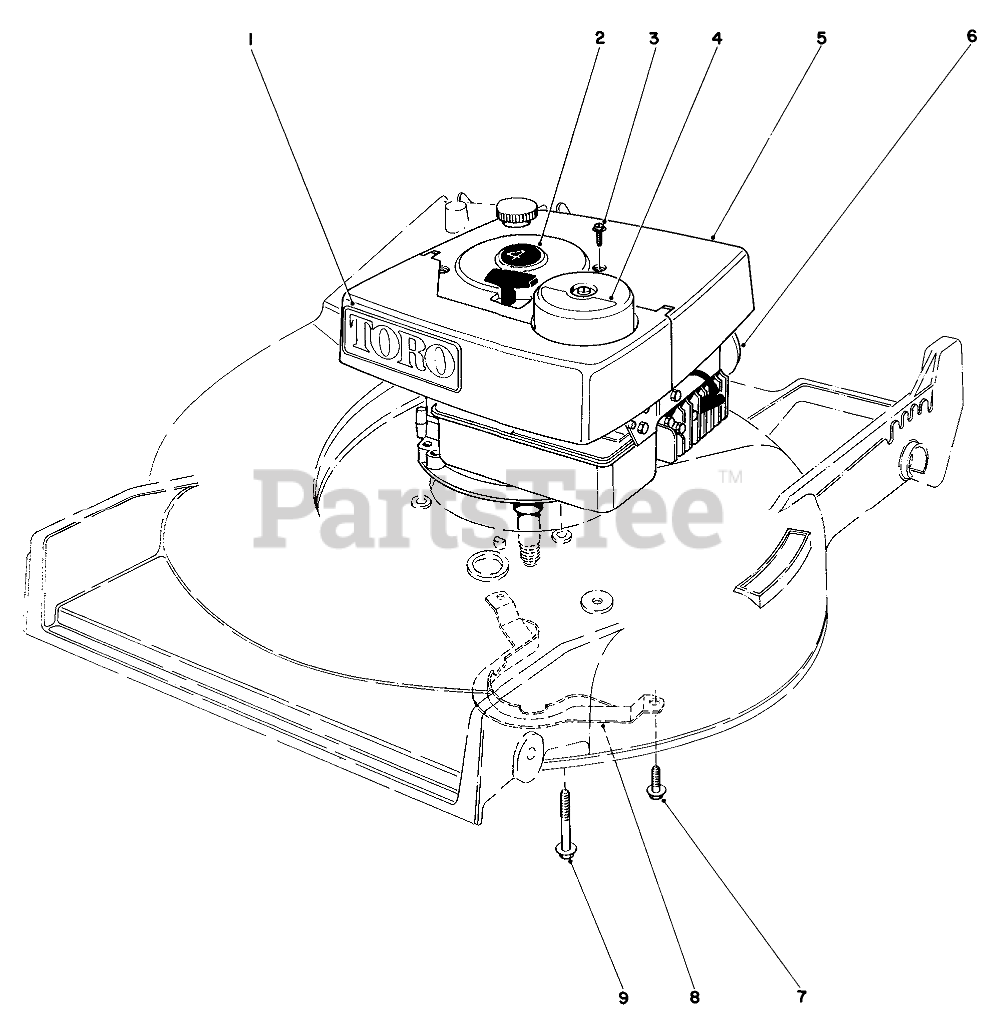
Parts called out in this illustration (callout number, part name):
1	Decal Tow
2	Decal-Shroud
3	TAPPING SCREW
4	Decal Air Filter
5	ENGINE SHROUD ASM
6	Engine
7	Screw
8	BELT GUIDE
9	3/8-16 X 2 CAPSCREW
